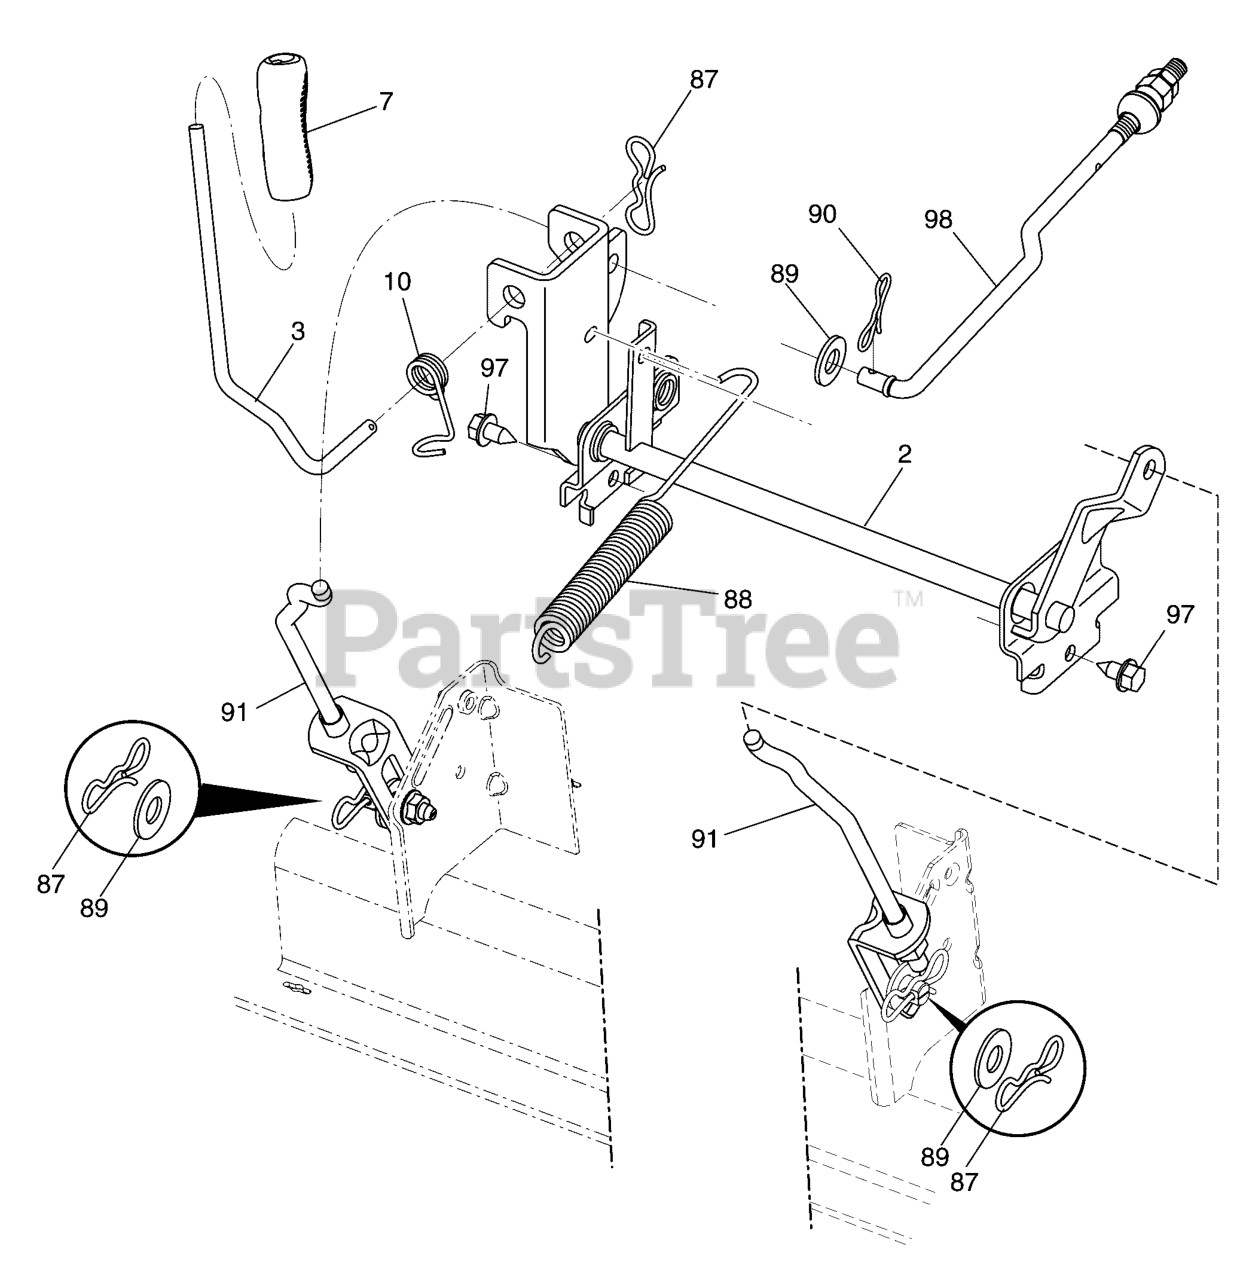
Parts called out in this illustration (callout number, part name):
2	SHAFT, Assembly Lift
3	LEVER, Assembly Lift RH
7	GRIP, Lever
10	SPRING, Torsion
87	PIN, Cotter, Bow Tie Lock, 7/16
88	SPRING, Lift Assist
89	WASHER, Clear Zinc
90	PIN, Cotter Bow Tie Lock, 5/16
91	LINK, Lift Suspension Mower Rear
97	SCREW, 3/8-16 x .75
98	LINK, Lift Suspension Mower Front
